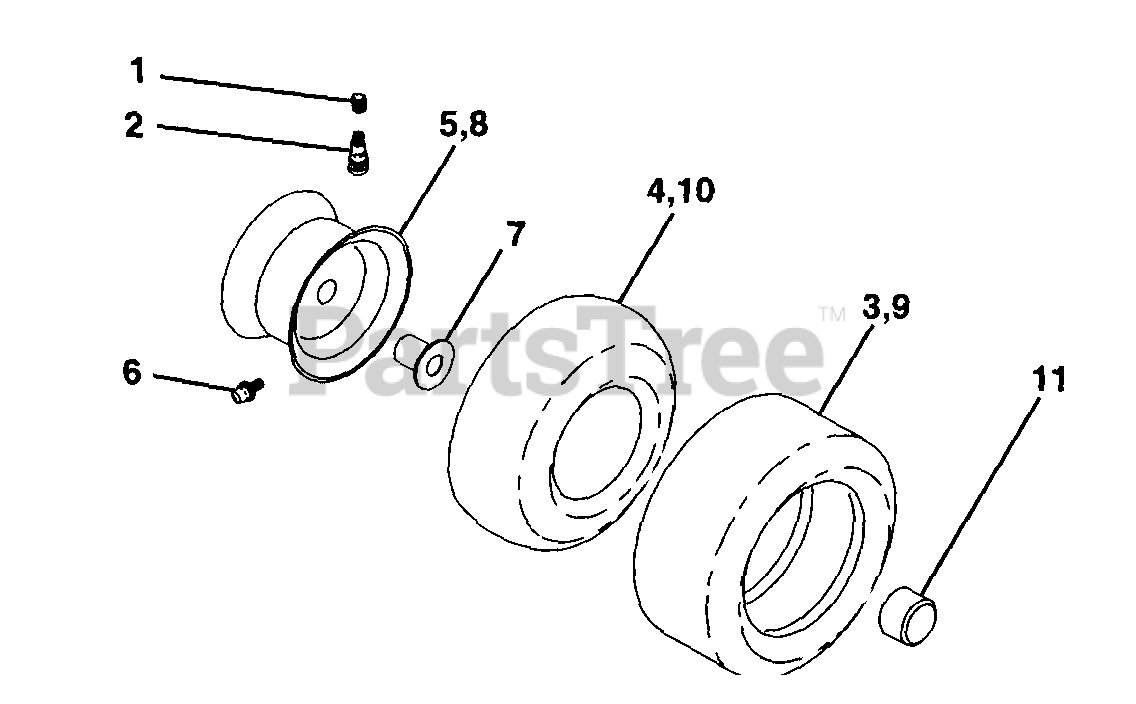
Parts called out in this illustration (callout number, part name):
1	Cap Valve Tire
2	Stem Valve
3	Tire F Ts 15 x 6 0 - 6 Service
4	Tube Front (Service Item Only)
5	Rim Asm 6" front Silver Service
6	Fitting Grease (Front Wheel Only)
7	Bearing Flange (Front Wheel Only)
8	Rim Asm 8" rear Silver Service
9	Tire R Ts 20 x 10-8 C Service
10	Tube Rear (Service Item Only)
11	Cap Axle Blk 1 50 x 1 00
